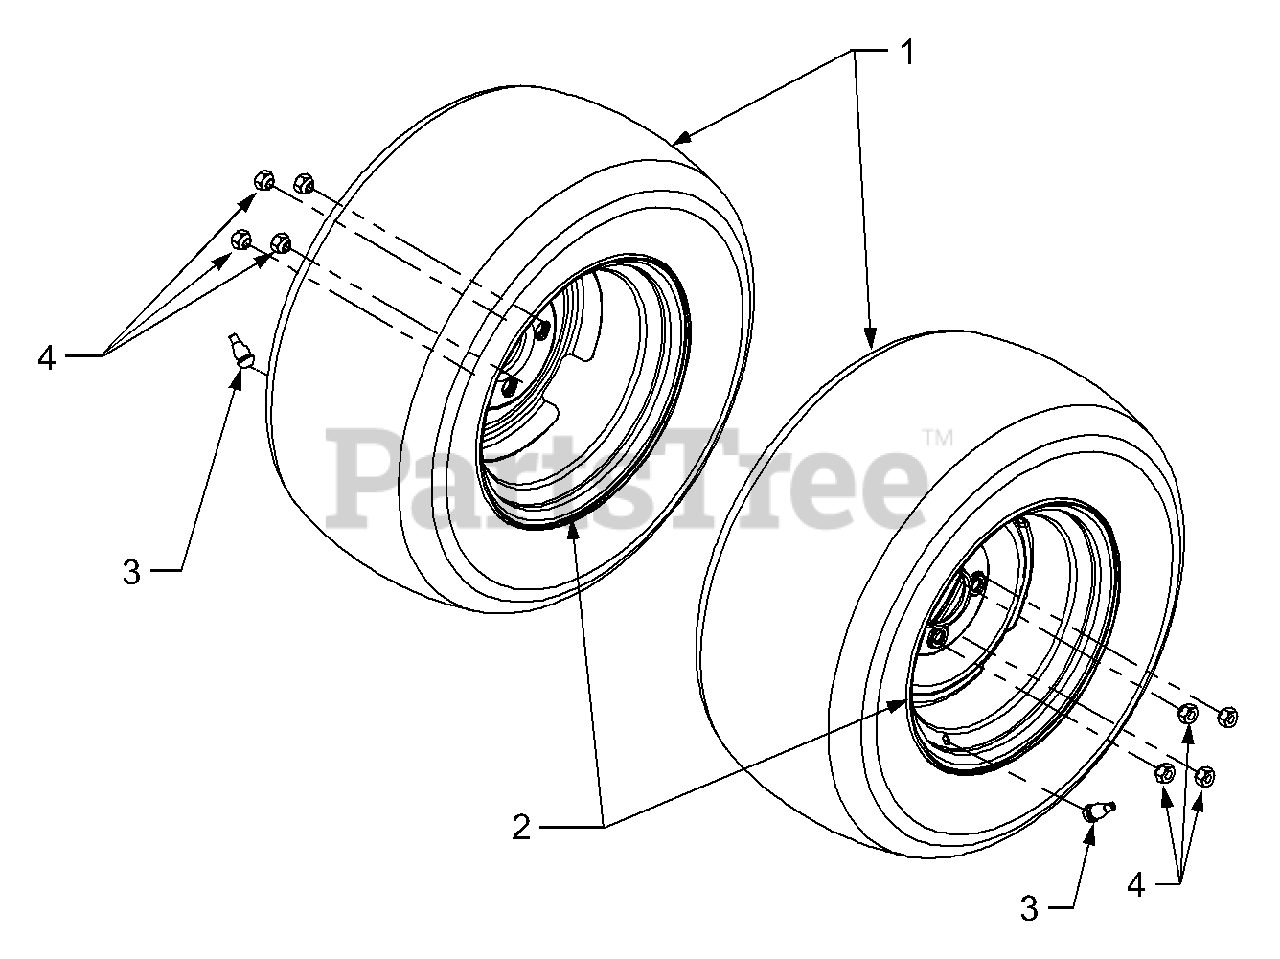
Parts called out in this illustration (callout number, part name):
1	Tire, Turf, 24 x 10.5 - 12
2	Rim Assembly, Wheel
3	Valve, Tubeless Air
4	Lug Nut, 7/16-14
